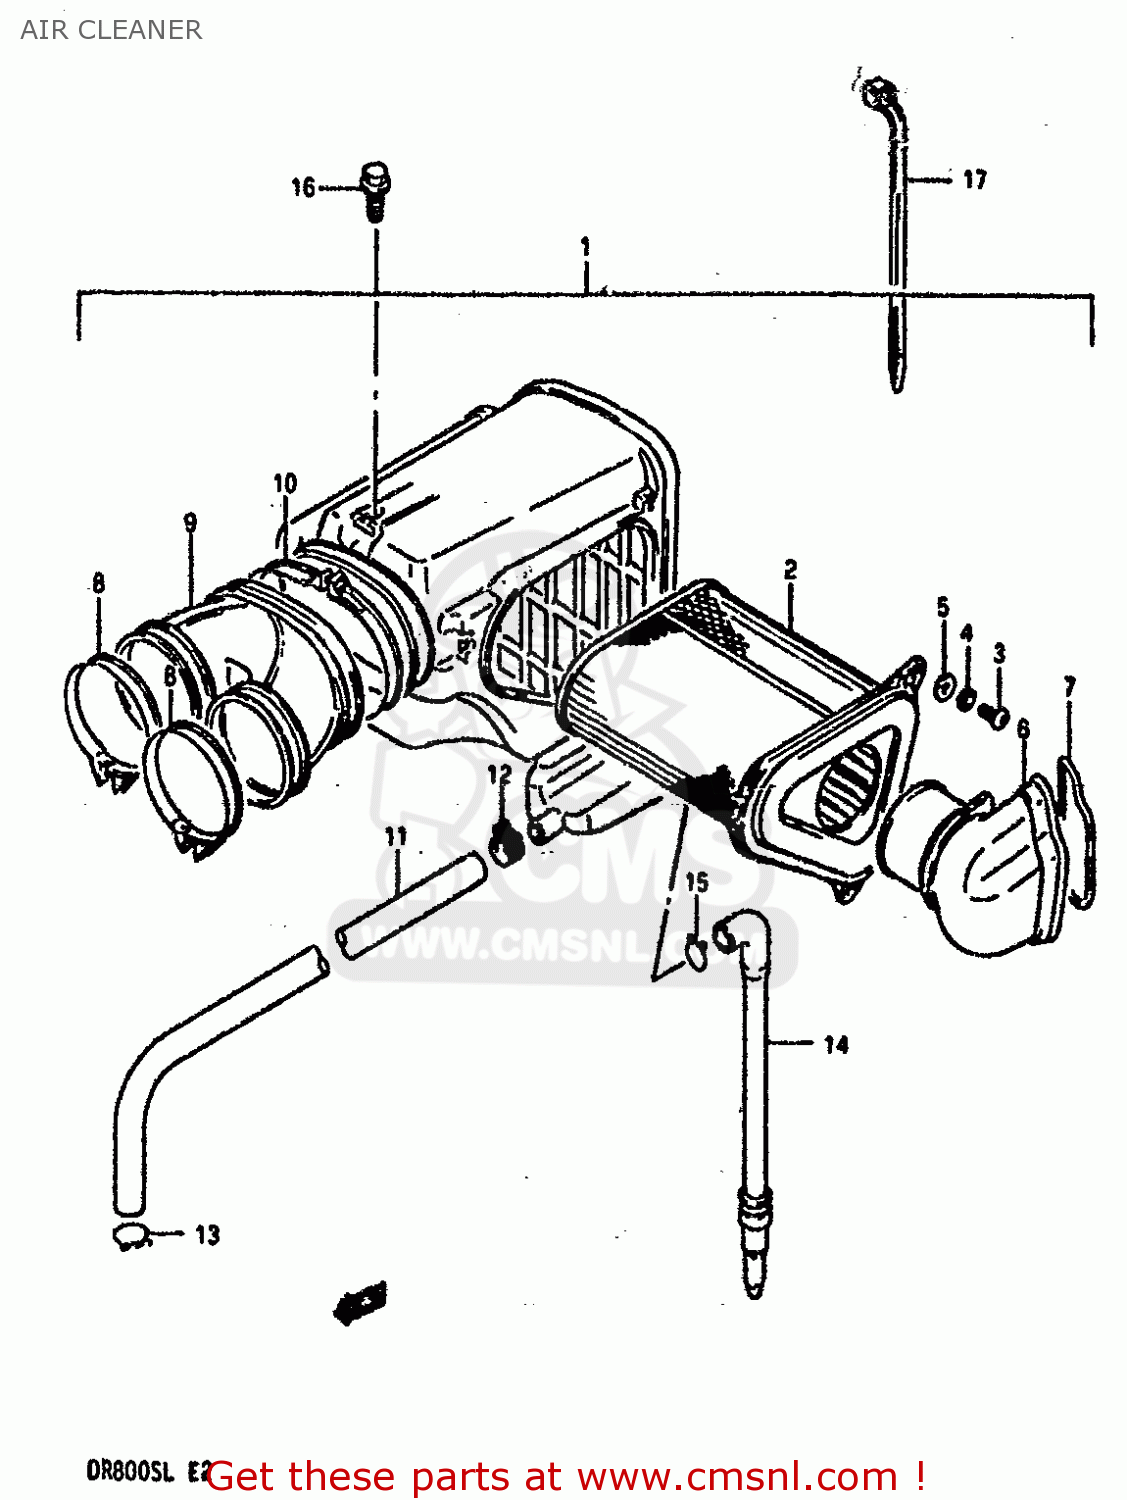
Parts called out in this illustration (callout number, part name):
1	CLEANER ASSY,AIR
2	FILTER ASSY
3	SCREW
4	LOCK WASHER
5	WASHER
6	TUBE,INLET
7	RING
8	CLAMP
9	TUBE,AIR CLEANER OUTLET
10	CLAMP
11	TUBE,BREATHER
12	CLIP
13	CLIP
14	TUBE,DRAIN
15	CLIP
16	BOLT 6X16
17	CLAMP(L:165)
